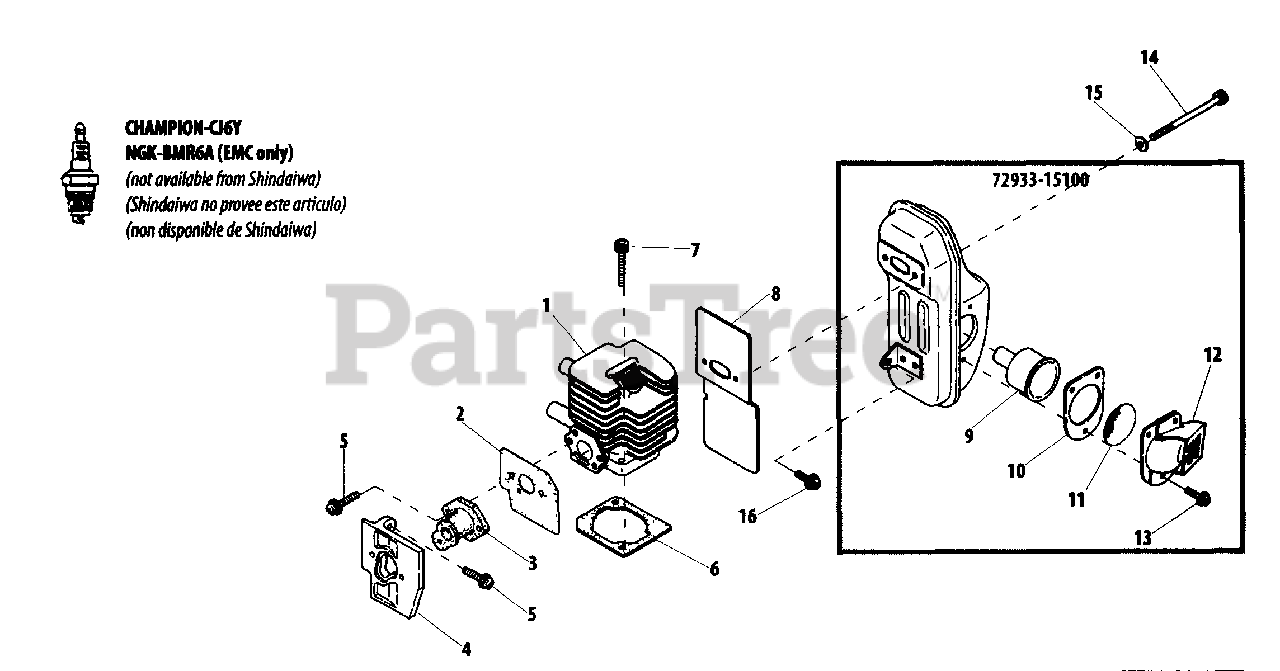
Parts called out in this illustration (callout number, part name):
1	CYLINDER
2	GASKET, INTAKE
3	BELLOWS, INTAKE
4	INSULATOR, INTAKE
5	SCREW
6	GASKET, CYLINDER
7	BOLT 5×20
8	GASKET, EXHAUST
9	GUIDE, EXHAUST
10	GASKET, EXHAUST
11	SCREEN, SPARK ARRESTER
12	GUIDE, EXHAUST
14	BOLT 5×55
15	WASHER, FLAT 5.5×10×0.8
16	SCREW
